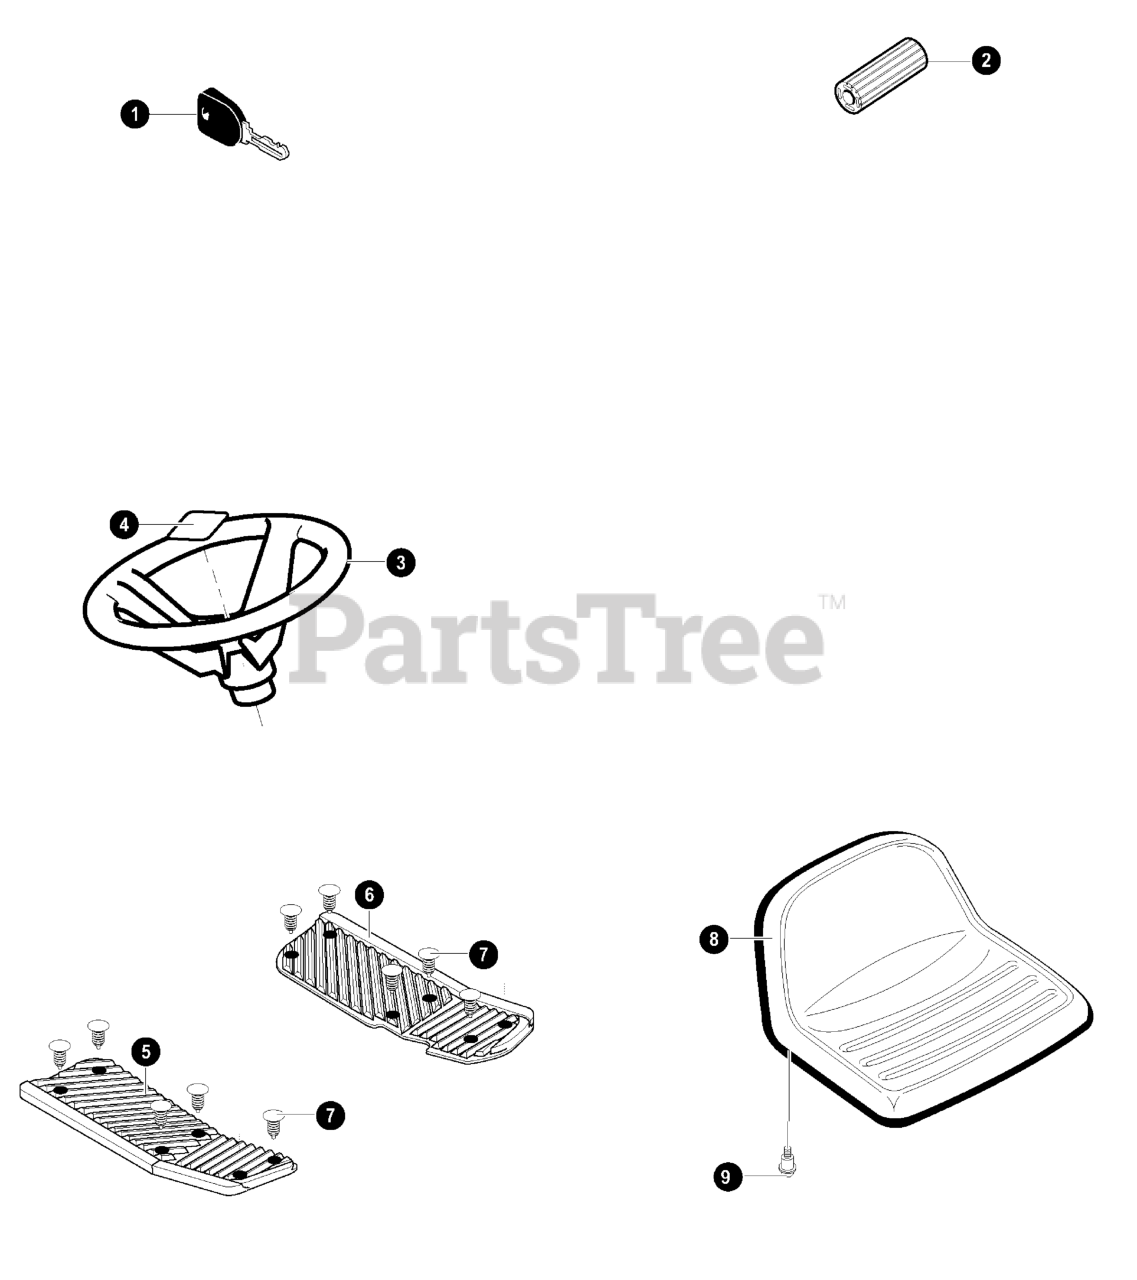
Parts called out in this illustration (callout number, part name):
1	IGNITION KEY
2	COVER, PEDAL BRK/CL
3	STEERING WHEEL
4	INSERT 4-SPOKE
5	FOOTREST PAD RH
6	FOOTREST PAD LH
7	FASTENER, RATCHET
9	BOLT, SHOULDER 5/16-18
